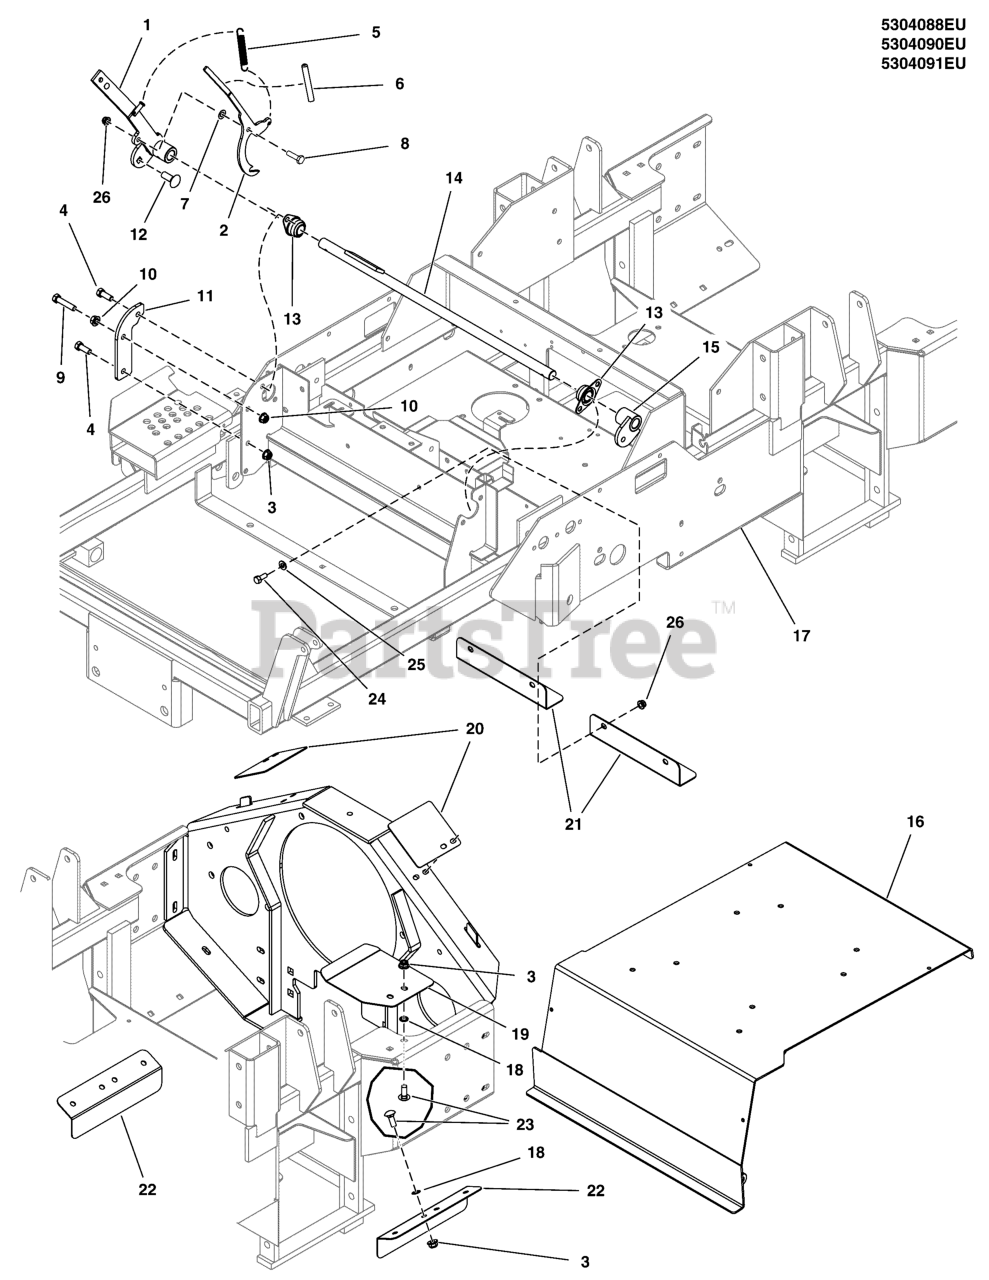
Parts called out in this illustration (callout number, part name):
1	WELD, HANDLE, BRAKE, 5100 - EU - RED
2	LEVER, BRAKE, 5100 - EU - RED
3	NUT, 3/8 - 16 HEX NYLOCK FLANGE
4	BOLT, 3/8-16 X 1" GD5 CZ
5	SPRING-EXT, .500 OD X 3.50 LG X .058 WR
6	COVER, VINYL HANDLE
7	WASHER,WAVE,M10
8	BOLT, 5/16-18 X 1-1/4" GD5 YZ
9	BOLT, 3/8-16 X 1-3/4" GD5 CZ
10	NUT, 3/8-16 Hex Large Serrated Flange
11	PLATE, SUPPORT, BRAKE, IS5100 - EU - RED
12	BOLT,3/8-16X1.000,RND HD CRRG,ZINC/CLEAR
13	BEARING, BRONZE FLANGE, 3/4"
14	WELD, SHAFT BRAKE LEVER - RED
15	PIVOT, LINKAGE MOUNT WELDMENT - BLK
16	WELD, SEAT PLATE, IS5100Z - EU
17	WELD, MAIN FRAME, IS5100 EU - RED
18	3/8 PUSHNUT BOLT RETAINER
19	PLATE, BELT GUARD,ENGINE MOUNT,TOP - RED
20	PLATE, FLY WHEEL GUARD, PUMP PLATE - RED
21	PLATE, PULLEY GUARD, CONTROL MOUNT - RED
22	PLATE, BELT GUARD,ENGINE MOUNT,BT - RED
23	BOLT,3/8-16X1.00,RD SH SQ NK,GR 5,ZC/CL
24	BOLT, 5/16-18 X 3/4 GD5
25	WASHER, 5/16" SAE
26	NUT, 5/16-18 HEX NYLOCK FLANGE NUT
